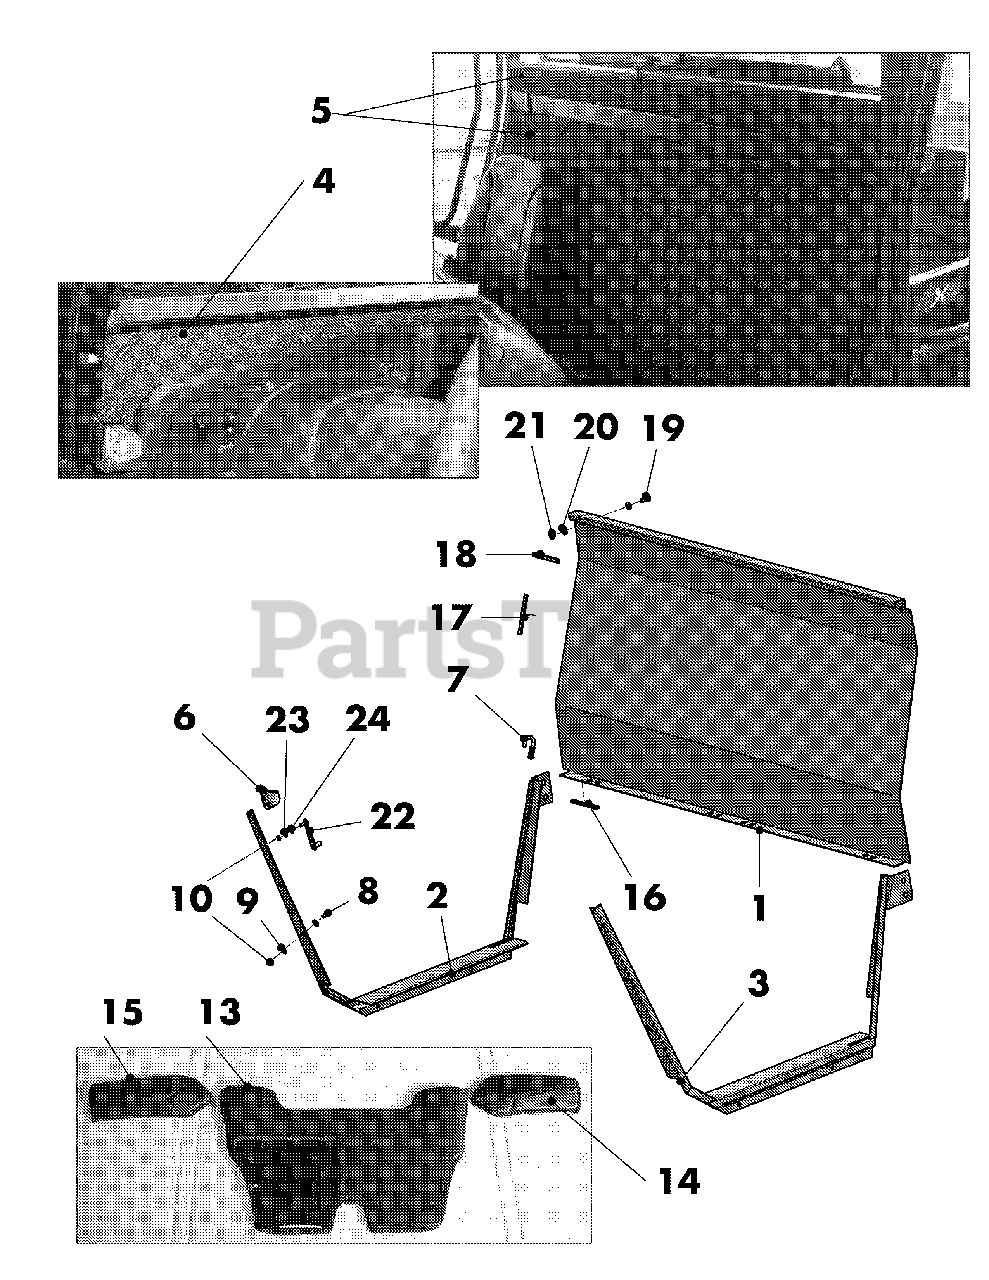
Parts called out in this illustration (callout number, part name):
2	Door Sill - RH
3	Door Sill - LH
4	Cover - Front Slat
5	Padding - Rear Plate
7	Mounting (Spring)
13	Covering - Center
